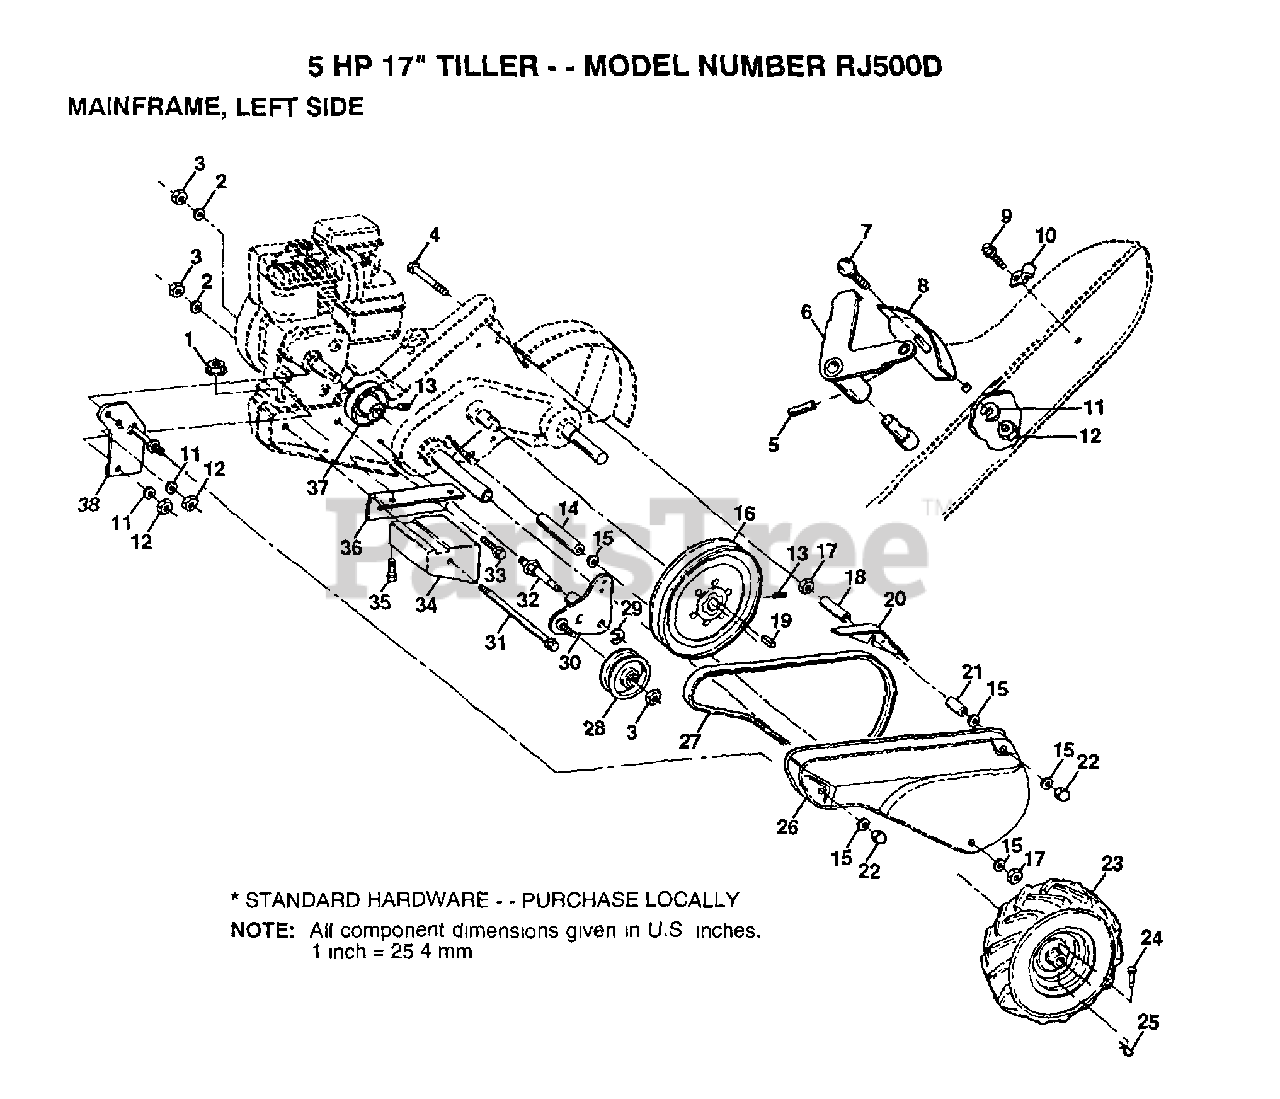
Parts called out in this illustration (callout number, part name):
2	LOCKWASHER
3	NUT.HEX.3/8-16UNC
4	BOLT TI
6	LEVER ASM CRT
7	BOLT
8	PANEL TI
10	CONDIUT CLIP T
11	LOCKWASHER
13	SET SCREW
14	SPACER
15	WASHER
16	"SHEAVE 10"" CRT"
17	NUT.HEX.5/16-18
18	SPACER CRT
19	KEY T
20	GUARD CRT
21	SPLIT SPACER
22	NUT TI
23	TIRE.CHV.13X5.0-6
24	RIVET.DRILL.1.75
25	RETAINER M
26	"GUARD, BELT"
27	BELT-V
28	PULLEY-IDLER TI
29	KLIP RING
31	BOLT CRT
32	SHIFT ARM CRT
33	BOLT
34	COUNTERWEIGHT CRT
35	BOLT.HEX.5/16-1.5
36	BRACKET LH CRT
37	ENGINE SHEAVE
38	BELT GUARD BRKT
